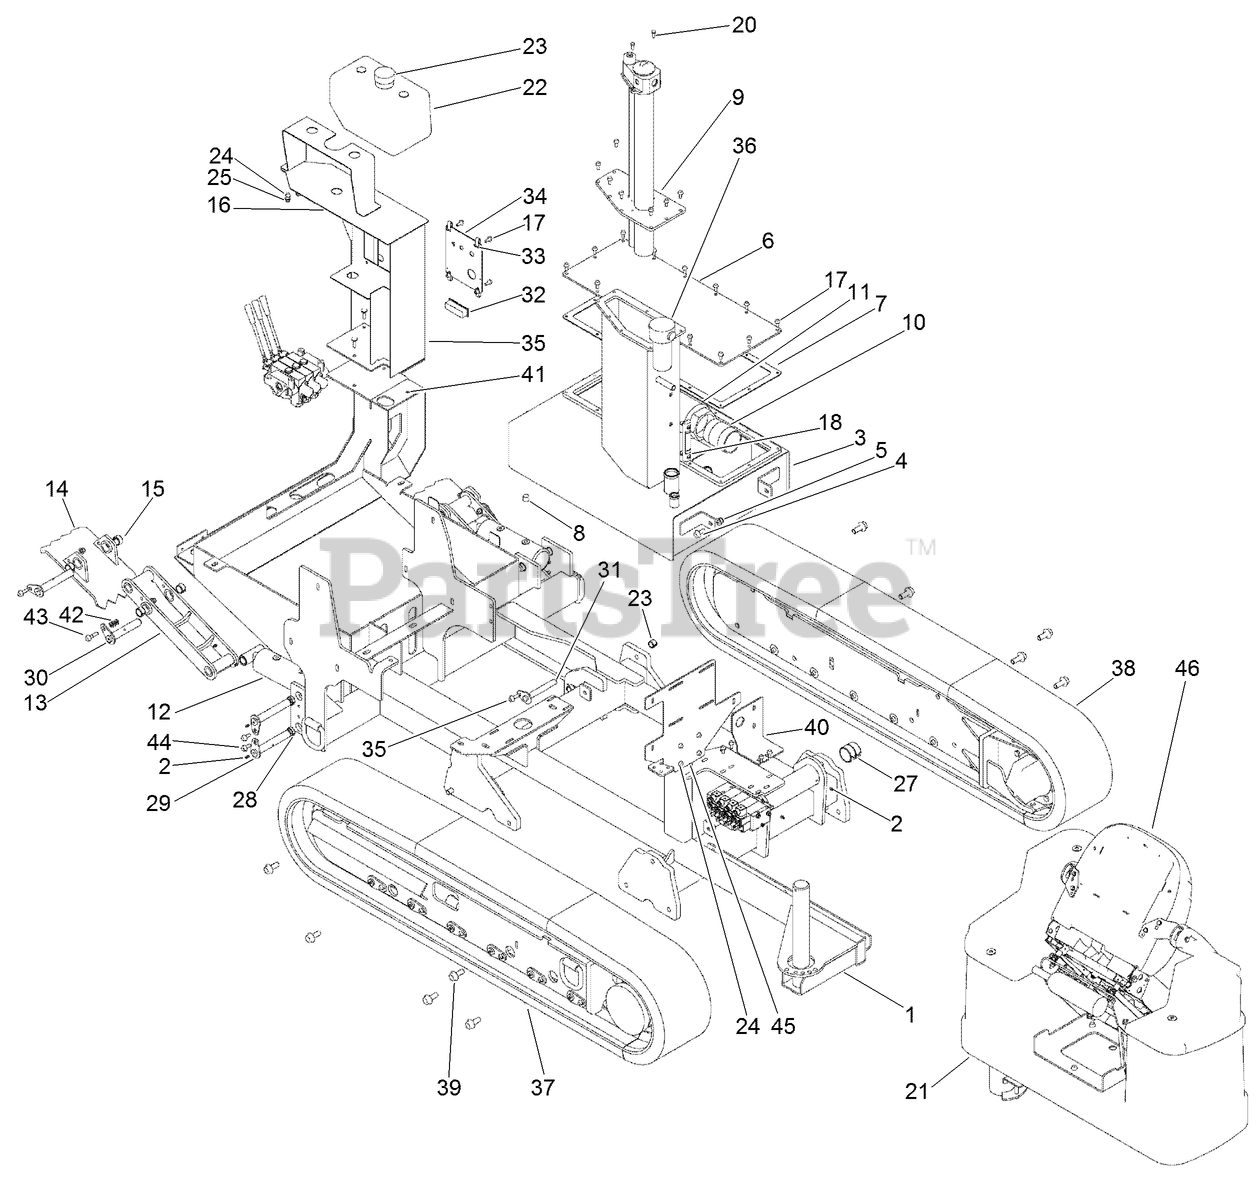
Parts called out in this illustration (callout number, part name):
1	FRAME - Main
2	FITTING-Lube 1/4-28 Tpr SAE-LT .54 Long
3	TANK - Hydraulic
4	SCREW, METRIC FLANGE w/BODY-M12 x 30
5	NUT-HHF, LOCK
6	PLATE - Hydraulic Tank Cover
7	GASKET-COVER LID, HYDRAULIC TANK
8	PLUG-PIPE, HEX SOCKET
9	WELDMENT - Hydraulic Tank Lid
10	NIPPLE-PIPE
11	STRAINER-SUCTION, 100 MESH
12	HYD CYLINDER ASM
13	WELDMENT - Stabilizer Leg
14	WELDMENT - Stabilizer Foot
15	BUSHING-SPRING
16	WELDMENT - Rear Controls Box
17	SCREW, METRIC FLANGE w/BODY - M8 x 20
18	GAUGE-SIGHT
20	BOLT - Hex Hd .312 x .750 GR8 PHC
21	ASSEMBLY - Operators Console
22	BOTTLE - Mud Pump System Anti-Freeze
23	CAP - Anti-Freeze Bottle
24	SCREW-HH
25	NUT-TORQUE, PREVAILING
27	BUSHING-SPRING
28	BUSHING-SPRING
29	PIN-FLAG
30	PIN-FLAG
31	PIN-FLAGGED
32	LATCH-TRIGGER, RAISED (W/LOCK)
34	PLATE - Rear Controls Panel
35	SCREW-HH
36	FILTER-HYD, 350PSI (6 MICRON)
37	ASSEMBLY - Track RH
38	ASSEMBLY - Track LH
39	SCREW-HHF
40	PLATE - Mount
41	NUT-FLANGE, NYLOCK
42	WASHER - 0.406 x 0.750 x 0.119 in CST ZND
43	SCREW-HHF
44	SCREW-FLANGE
45	PLATE - Fuse Box Mount
46	PLATE - Operators Manual Case Mounting
